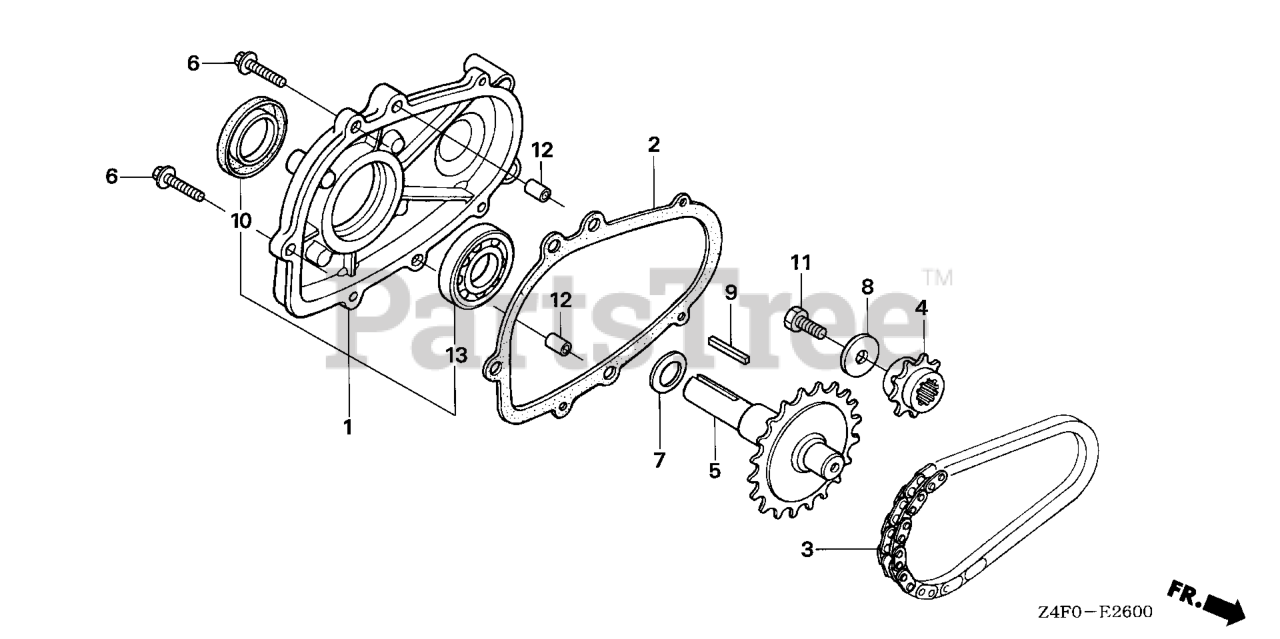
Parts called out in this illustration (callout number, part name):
1	COVER ASSY., CHAIN CASE
2	GASKET, CHAIN CASE COVER
3	CHAIN, P.T.O. DRIVE (DID270S-DHA-36LE)
4	SPROCKET, DRIVE (14T)
5	SHAFT, P.T.O. (28T)
6	BOLT, FLANGE (6X28) (CT200) Use up to Engine SN 1530314.
7	SPRING, THRUST
8	WASHER (8MM)
9	KEY (5X5X33)
10	OIL SEAL (25X41X6)
11	BOLT, HEX. (8X25)
12	PIN A, DOWEL (8X14)
13	BEARING, RADIAL BALL (6205)
